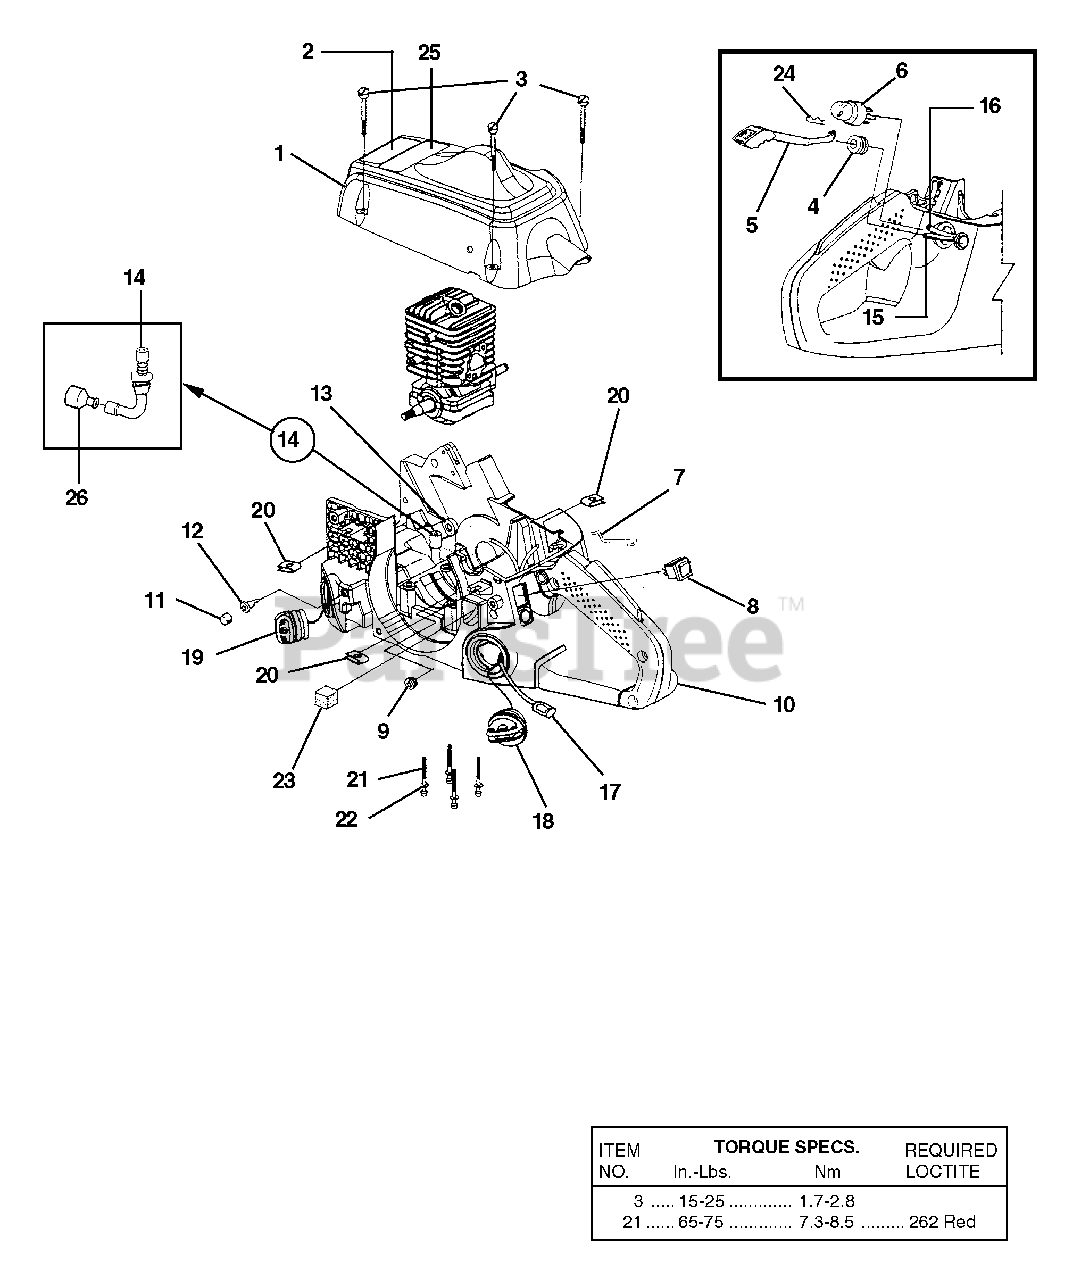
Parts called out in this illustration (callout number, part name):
1	Cylinder Cover Kit
2	Safety Decal
3	Screw-Slotted Pan Hd.
4	Grommet
5	Rod, Choke
6	Bulb,Air Purge
7	Throttle Wire
8	Switch, Rocker
9	Grommet-Split
10	Engine Housing
11	Element, Filter (Bronze)
12	Duck Bill Valve
13	Oil Outlet Grommet
14	Oil Intake Tube
15	Rubber Tubing (5 1/2")
16	Rubber Tubing (8 1/2")
17	Fuel Filter
18	Fuel Cap w/Retainer
19	Oil Cap w/Retainer
20	Speed Nut ("U-Type")
21	Screw, Cap-Socket Hd. (10-24 x 2")
22	Washer
23	Pre Filter
24	Spring Clip (Choke Rod)
25	Kick back-Decal
26	Oil Filter
